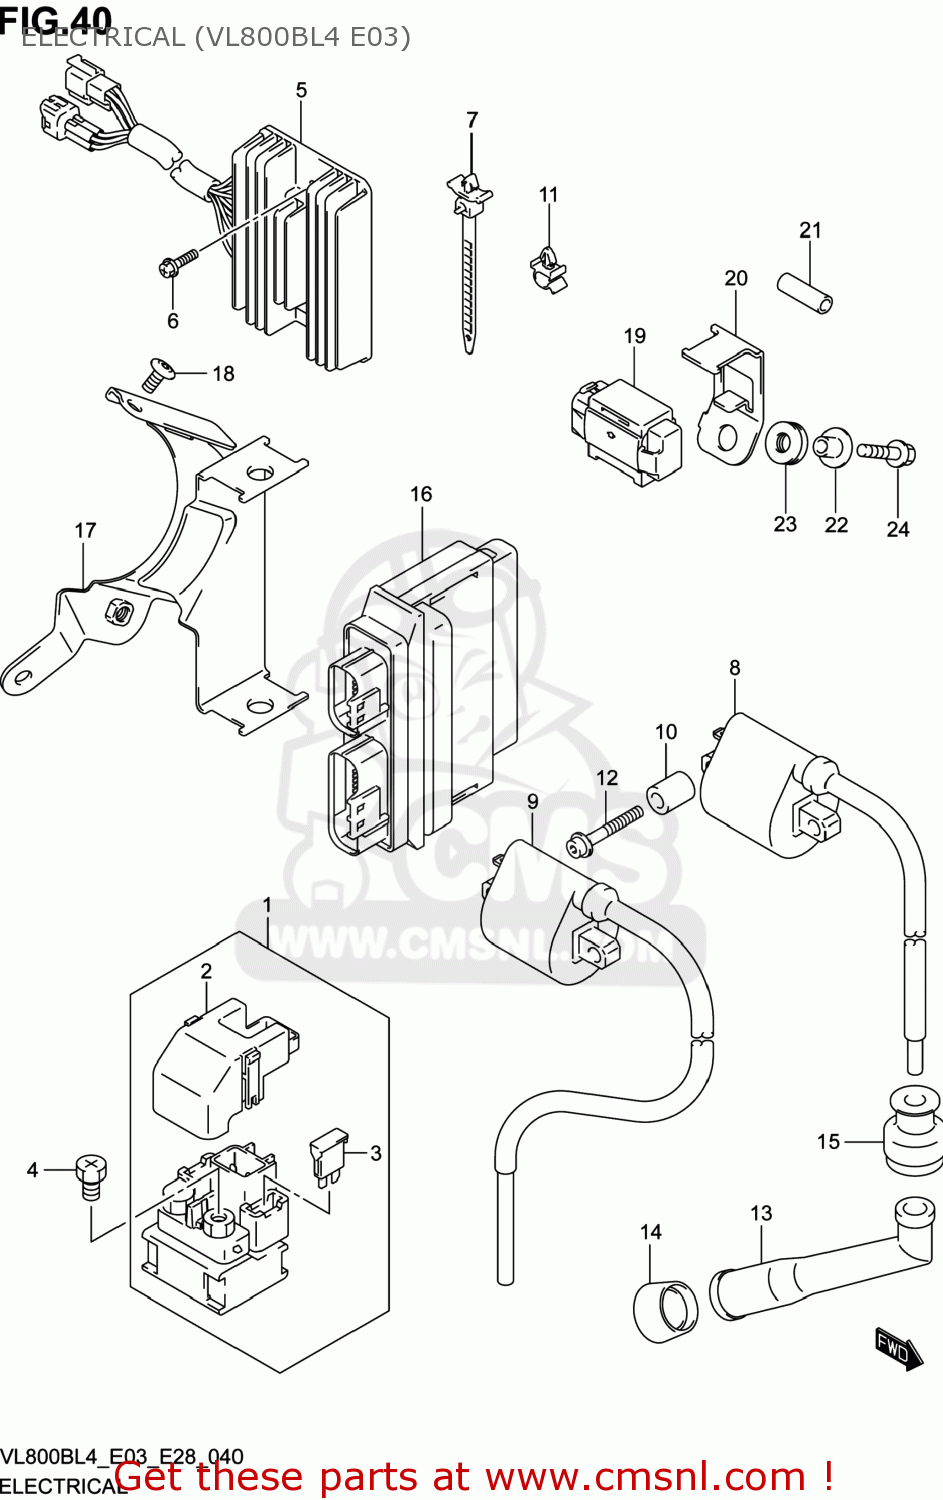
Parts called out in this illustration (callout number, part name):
1	RELAY ASSY,STARTING MOTOR
2	COVER
3	FUSE(30A)
4	SCREW(6X8)
5	RECTIFIER ASSY
6	SCREW
7	CLAMP(L:90)
8	COIL ASSY,IGNITION
9	COIL ASSY,IGNITION
10	SPACER(6.4X10X18)
11	CLAMP
12	BOLT(5X35)
13	CAP,SPARK PLUG
14	SEAL,SPARK PLUG
15	SEAL,HIGH TENSION CORD
16	CONTROL UNIT,FI
17	BRACKET,FI CONTROL UNIT
18	SCREW(6X12)
19	SENSOR ASSY,FUEL CUT
20	BRACKET,FUEL CUT SENSOR
21	HOSE(5X8.2X600)
22	SPACER(6.2X8.4X6.9)
23	CUSHION
24	BOLT
